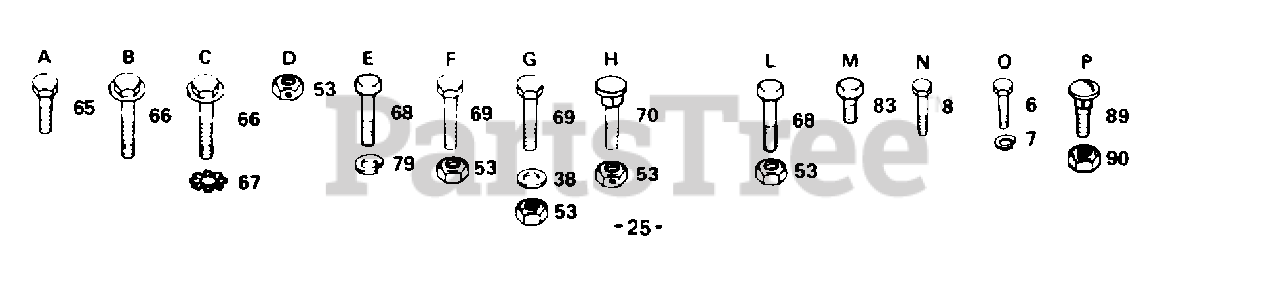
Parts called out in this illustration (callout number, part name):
6	BOLT
7	LOCKWASHER
25	HUB CAP
38	WASHER
65	SCREW
66	SCREW LT
67	LOCKWASHER
69	BOLT
70	BOLT
79	LOCKWASHER
83	SCREW
89	BOLT
90	NUT CROWN LOCK
